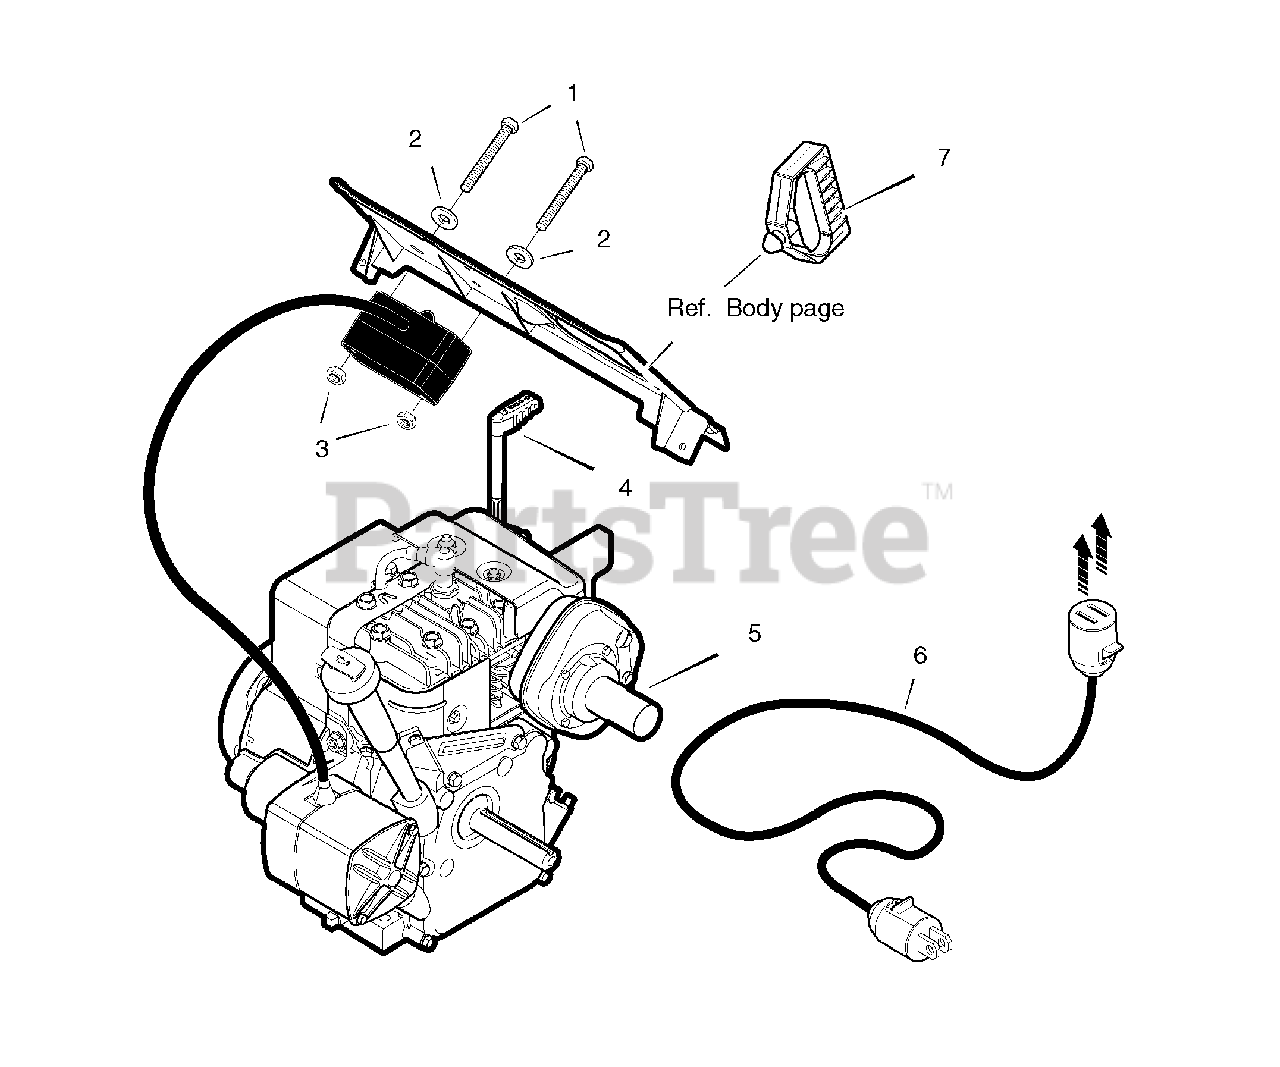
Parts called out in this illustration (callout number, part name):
1	SCREW, No. 8-32 x 3.00
2	WASHER, FLAT No. 8
3	NUT, Keps No. 8
4	* LEVER, Choke
5	Kit, Muffler Assembly
5-1	* MUFFLER
5-2	* GASKET, Muffler
5-3	* BOLT, Muffler
5-4	WASHER, Split Lock
5-5	NUT, Hex 5/16-18
5-6	BOLT, Hex 5/16-18
6	CORD, Electric, 10FT. 110V
6	CORD, Electric 220V
7	GRIP, Mitten
